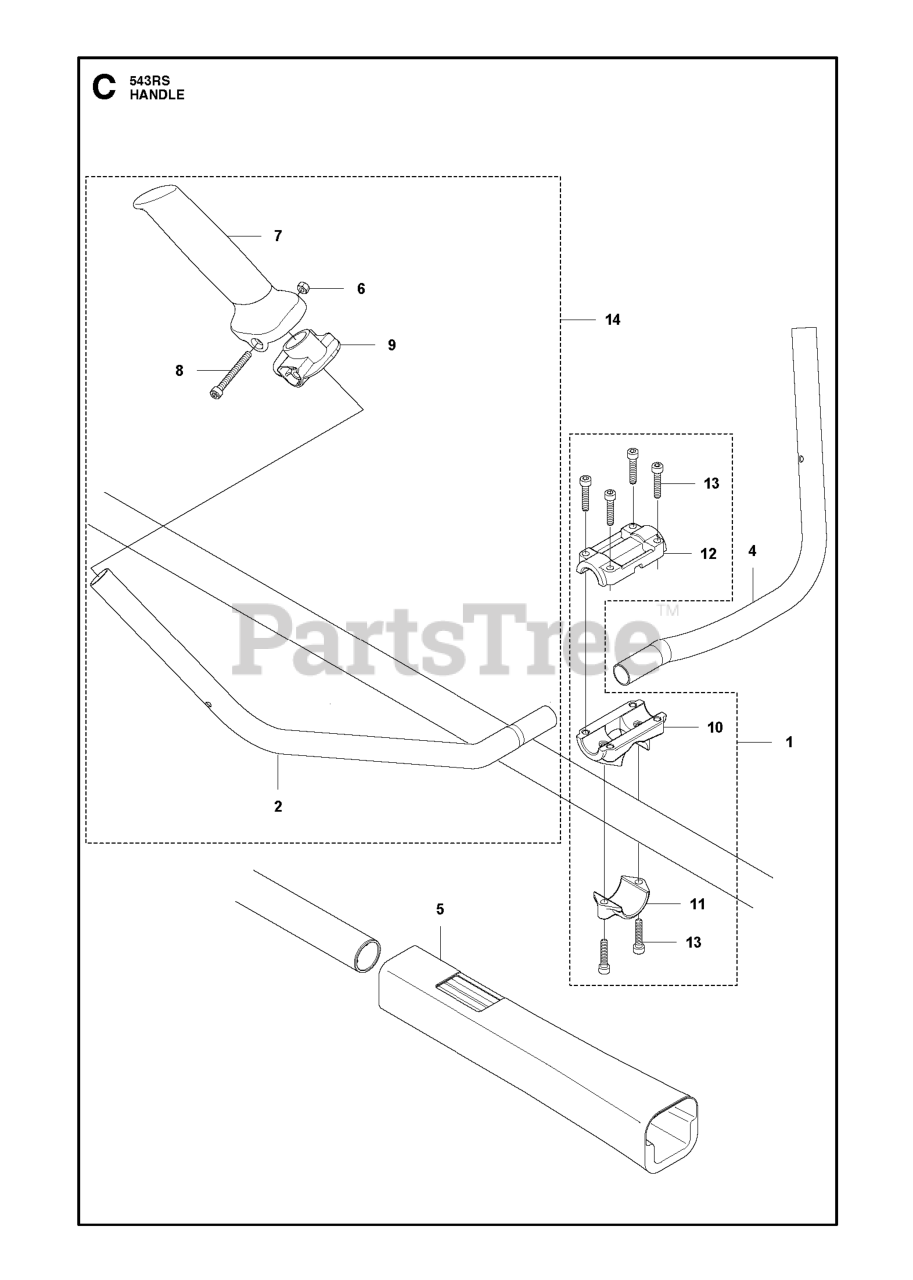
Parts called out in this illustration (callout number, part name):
1	HANDLE BRACKET ASSY 243R
5	PROTECTOR (RPLS 405017110)
6	NUT
10	BRACKET Z354314112
11	CAP-L Z354314121
14	HANDLE(L)-A
